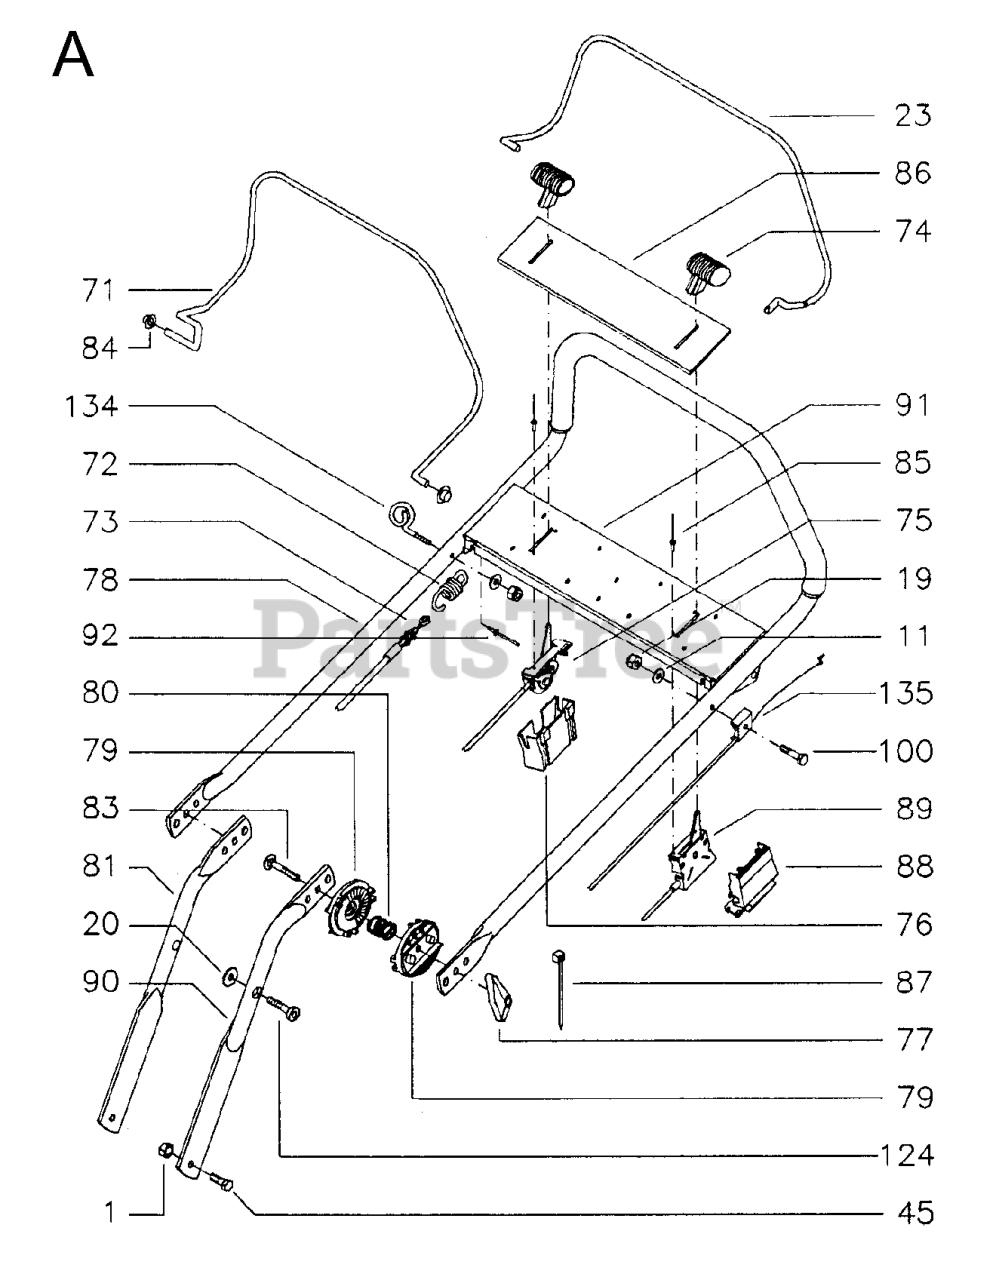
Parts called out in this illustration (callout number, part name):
1	LOCKNUT M8
19	LOCKNUT M6
45	SCREW M6S 8X25
77	WINGNUT
89	CONTROL
90	HANDLE
92	RIVET
100	BOLT FLANGE
134	CABLE GUIDE
